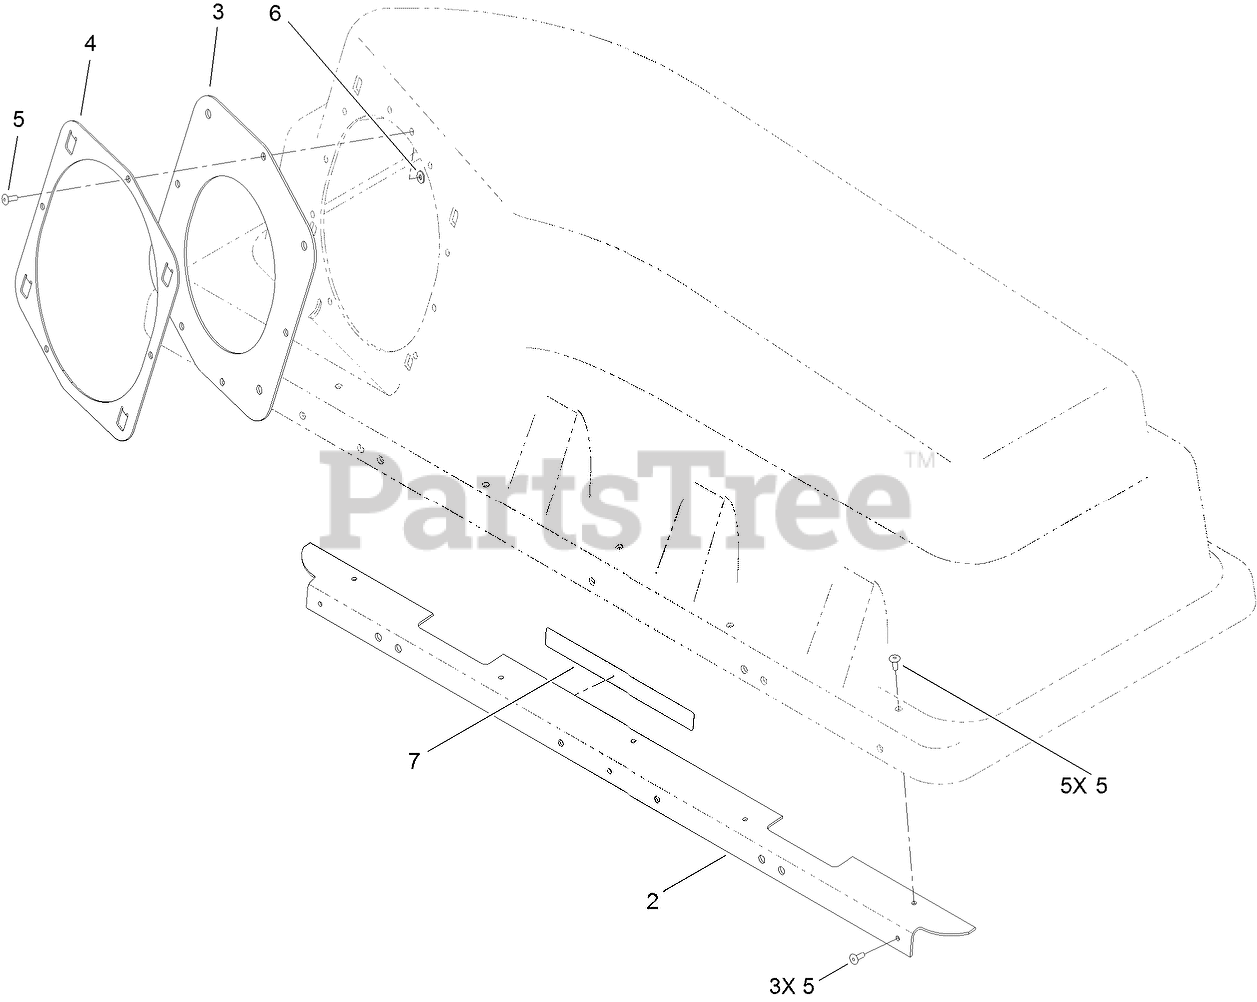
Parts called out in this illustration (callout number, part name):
2	STIFFENER-BAGGER TOP
3	GASKET
4	RING-RETAINER
5	RIVET-BLIND
6	WASHER-FLAT
7	DECAL-CAUTION, BAGGER
